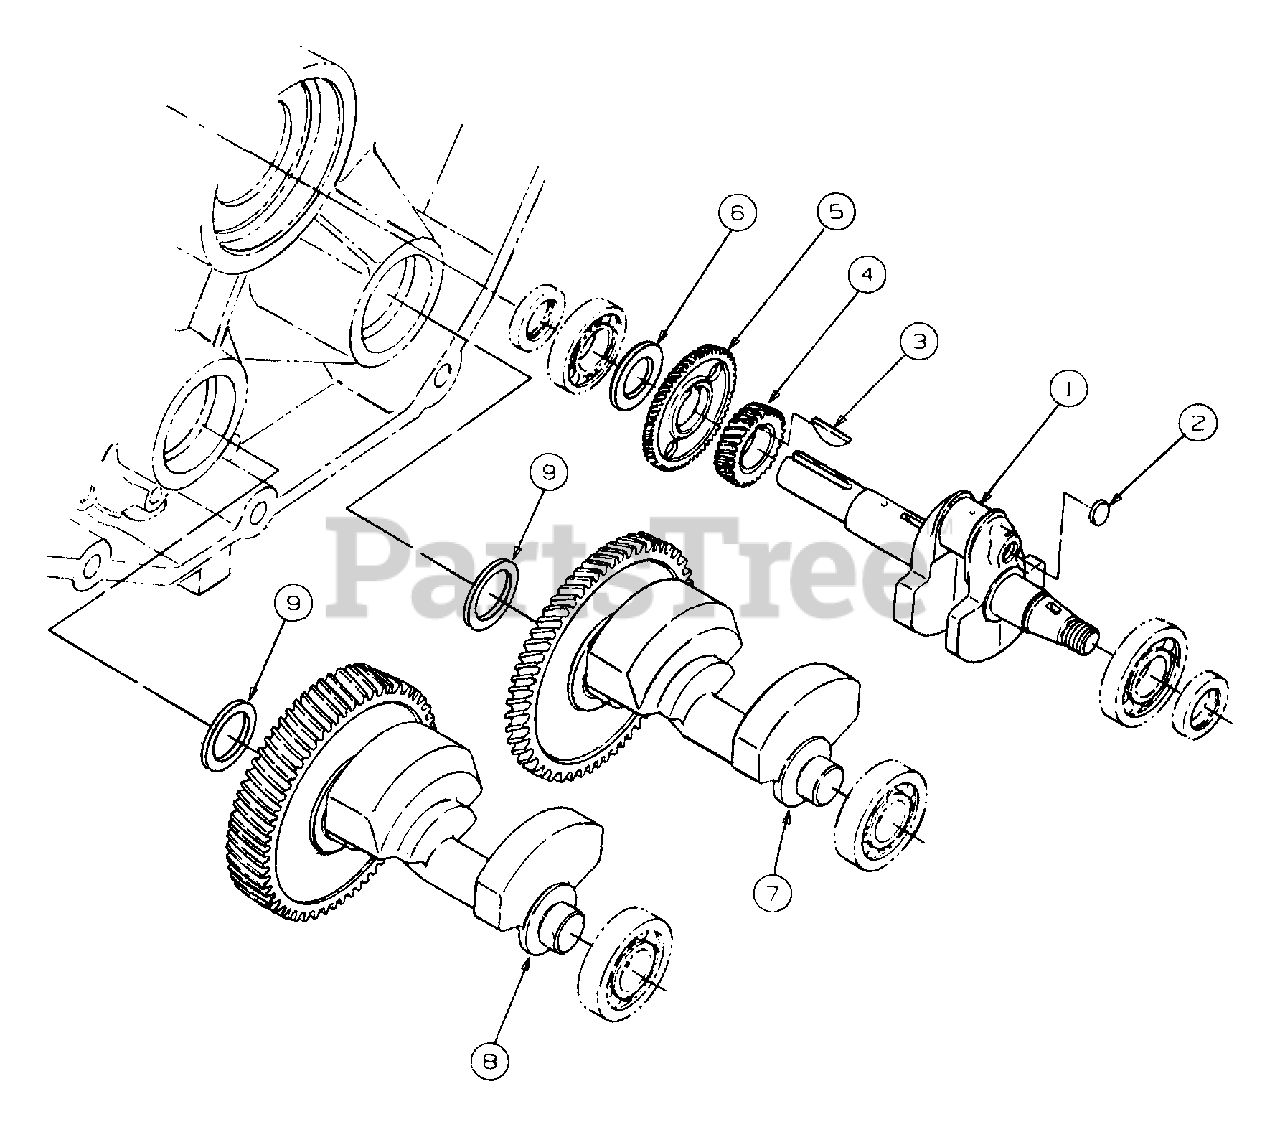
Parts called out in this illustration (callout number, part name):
1	Crankshaft Assy
2	Plug, Expansion
3	Key, Crankshaft Gear
4	Gear, Crankshaft
5	Gear, Balancer
6	Shim, Crankshaft, .2mm
7	Shaft Assy, Balancer
8	Shaft Assy, Balancer
9	Shim, Balancer Shaft, .5mm
